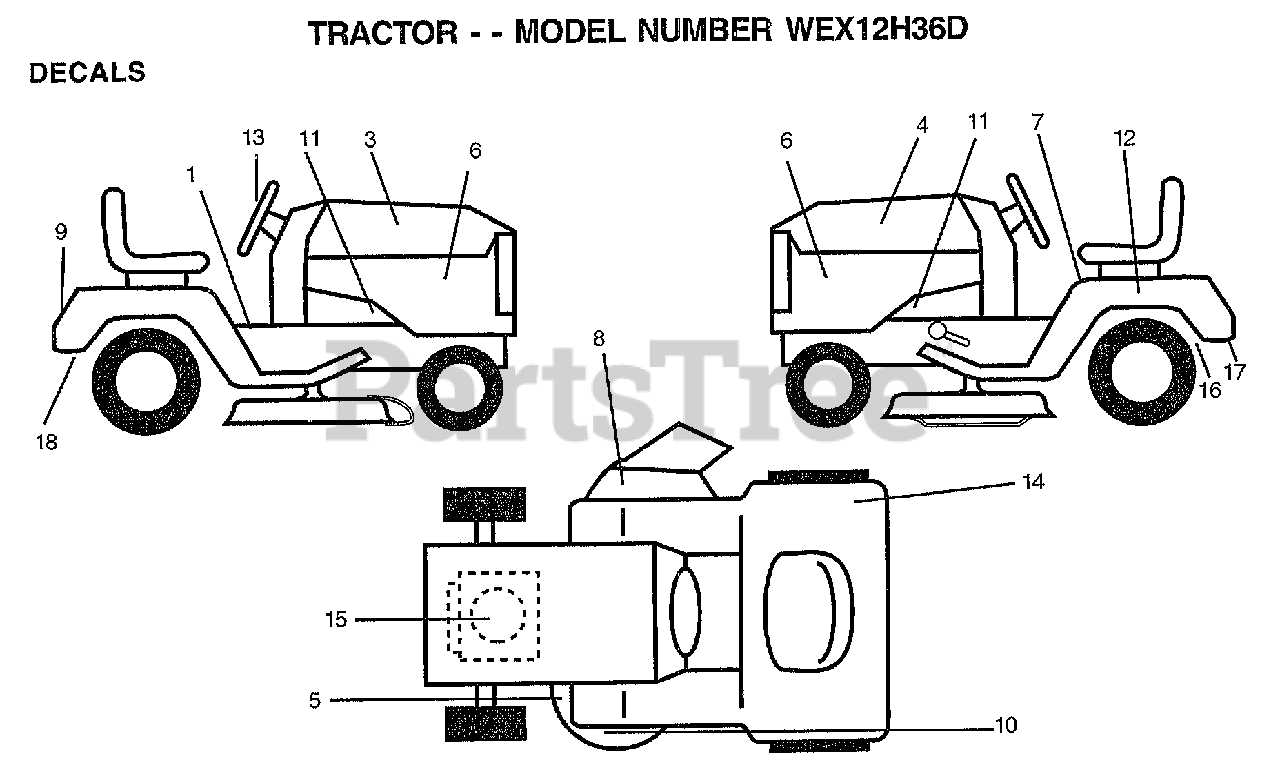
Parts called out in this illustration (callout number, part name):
1	DECAL CLUTCH/BRAK
3	DECAL.HOOD.RH
4	DECAL.HOOD.LH
5	DECAL.V.BELT
6	"DECAL,PNL SIDE"
7	DECAL.READ.O.MANU
8	DECAL.DANGER.CUTF
9	DECAL.FENDER.LOGO
10	DECAL, DECK GRASSEATER
11	"DECAL CHASSIS,HOT"
12	DECAL.BATRY.3-3908
13	DECAL INSRT STEER
15	DECAL, ENGINE
16	DECAL.DRAWBAR.LDL
17	DECAL.DRAWBAR.CTL
18	DECAL.EURO.ST.CE.
